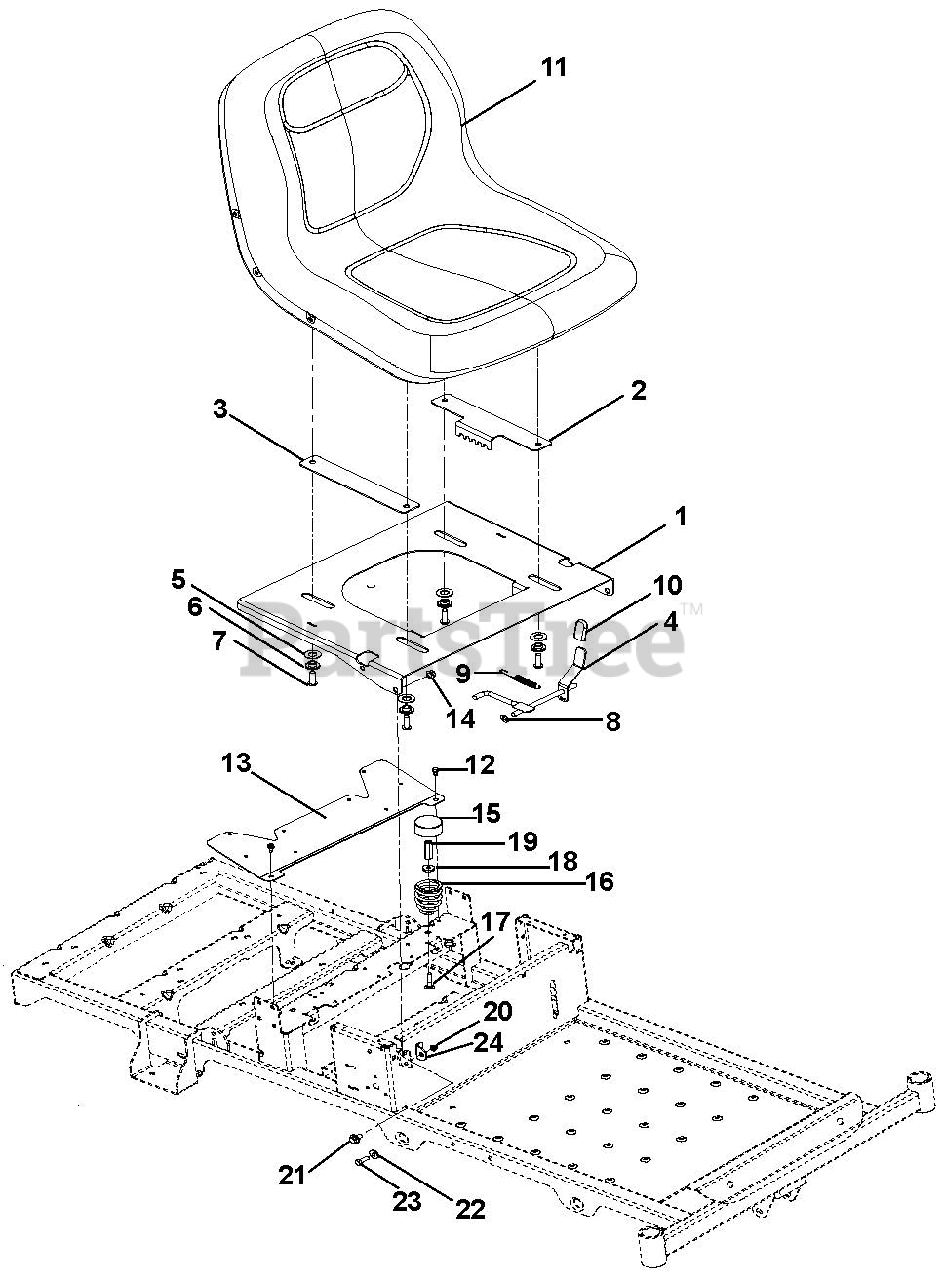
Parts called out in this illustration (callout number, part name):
1	Plate, Adjustable Seat
2	Plate, Adjustable Seat Track
3	Plate Adjustable Seat Slide
4	Weldment, Adjustable Seat Latch
5	Washer, Flat Steel .505 x 1.00 x .062
6	Bushing, Flange .32 x .500 x .344 x .880
7	Screw, Socket Head, Button Head .31-18 x 1.00
8	Push Nut 5/16
9	Spring Tension .043 x .44 x 3.31 Weldment 5.8
10	Grip, Seat Lever, Grey
11	Seat, Milsco XB180 Grey
12	Screw, Tapping .25-20 x .50 Hex Washer Head Thread
13	Guard, Fan
14	Nut, .38-16 Locking Top Flange
16	Spring, Seat
17	Bolt, Round Head Square Neck .31-18 x 1.50
18	Washer, Flat Steel .328 x .87 x .179
19	Nut, Coupling 5/16-18 x 1.75
20	Nut, 5/16-18 Flange Nyloc
21	Bolt, Shoulder .375-16 x .135
22	Bushing, Flange .325 x .499 x .26 x .88
23	Bolt, Hex .31-18 x 1.00
24	Bracket, Seat Stop
